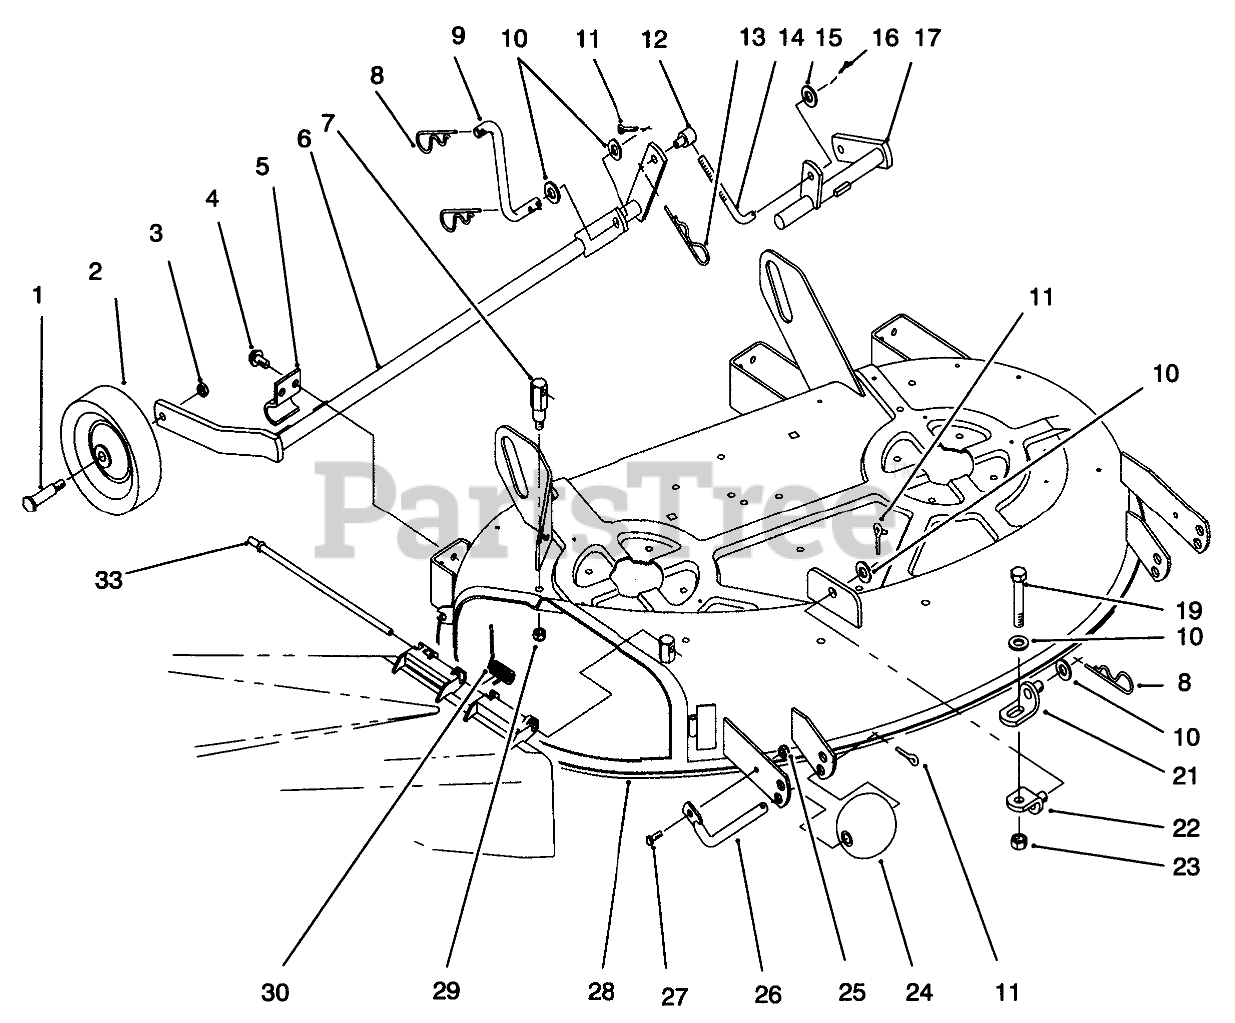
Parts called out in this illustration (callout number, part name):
1	BOLT-SHOULDER
2	WHEEL
3	NUT-HEX
4	SCREW-HWH, TAPTITE
6	SHAFT-RH
7	PIVOT POST - REAR
8	PIN-COTTER, HAIR
9	LINK-REAR
10	WASHER-FLAT
11	PIN-COTTER
12	TRUNNION
13	PIN-HAIR
14	ROD-LIFT
15	WASHER-FLAT
16	PIN-COTTER
17	SHAFT-LH
19	SCREW-HH
21	BRACKET-LIFT, LOWER
22	BRACKET-LIFT, UPPER
23	NUT-JAM
24	ROLLER
25	NUT-LOCK, NI
26	SHAFT-ROLLER
27	SCREW-HH
28	DECK ASM
29	NUT-LOCK, NI
30	SPRING
33	ROD-HINGE DEFLECTOR
